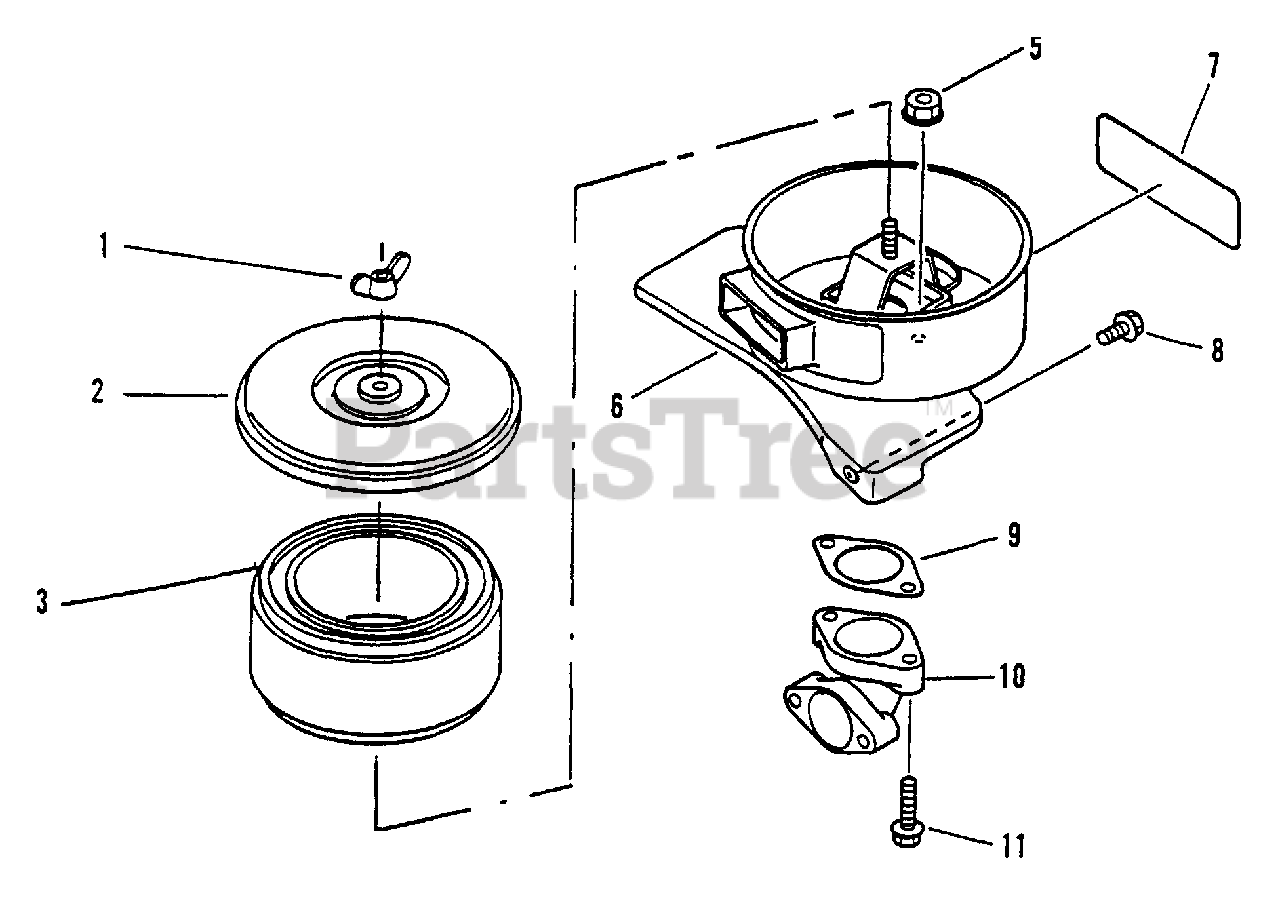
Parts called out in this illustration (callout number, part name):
1	WINGNUT - 6
2	COVER, AIR FILTER
3	FILTER, AIR
5	NUT - 6 -- FLANGE
6	CASE, AIR FILTER
7	LABEL - CAUTION
8	SCREW - 6X10
9	GASKET, INTAKE
10	MANIFOLD, INTAKE
11	BOLT - 6X25
